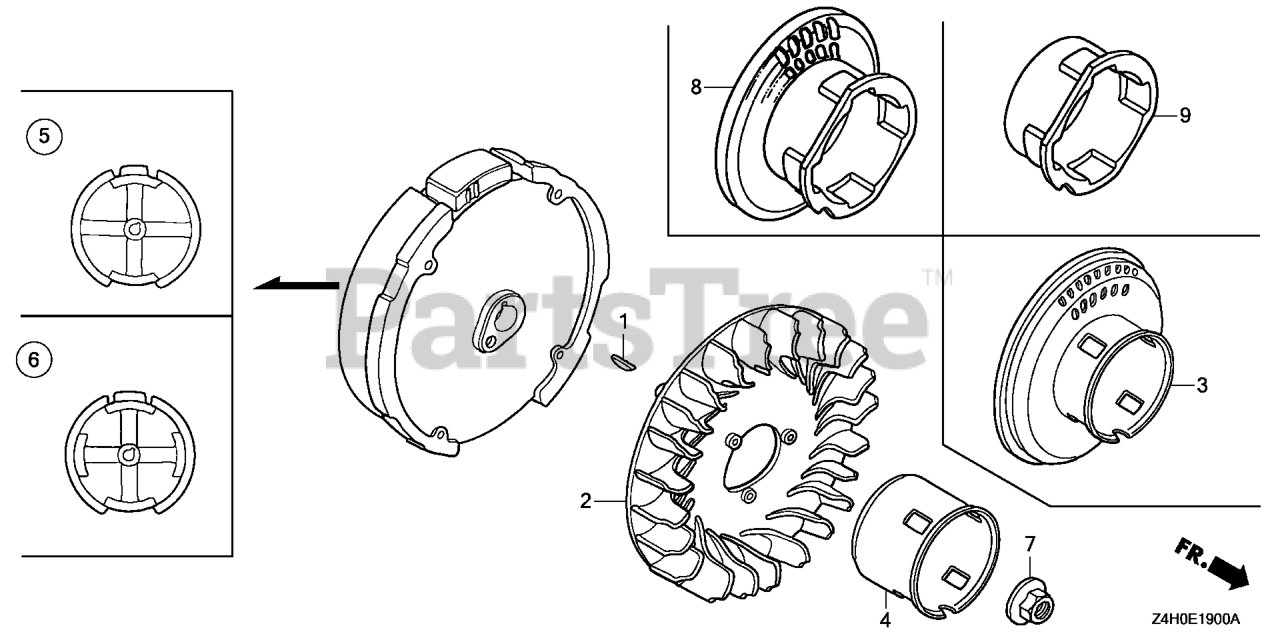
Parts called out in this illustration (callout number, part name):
1	KEY, SPECIAL WOODRUFF (25X18)
2	FAN, COOLING
7	NUT, SPECIAL (14MM)
9	PULLEY, STARTER
